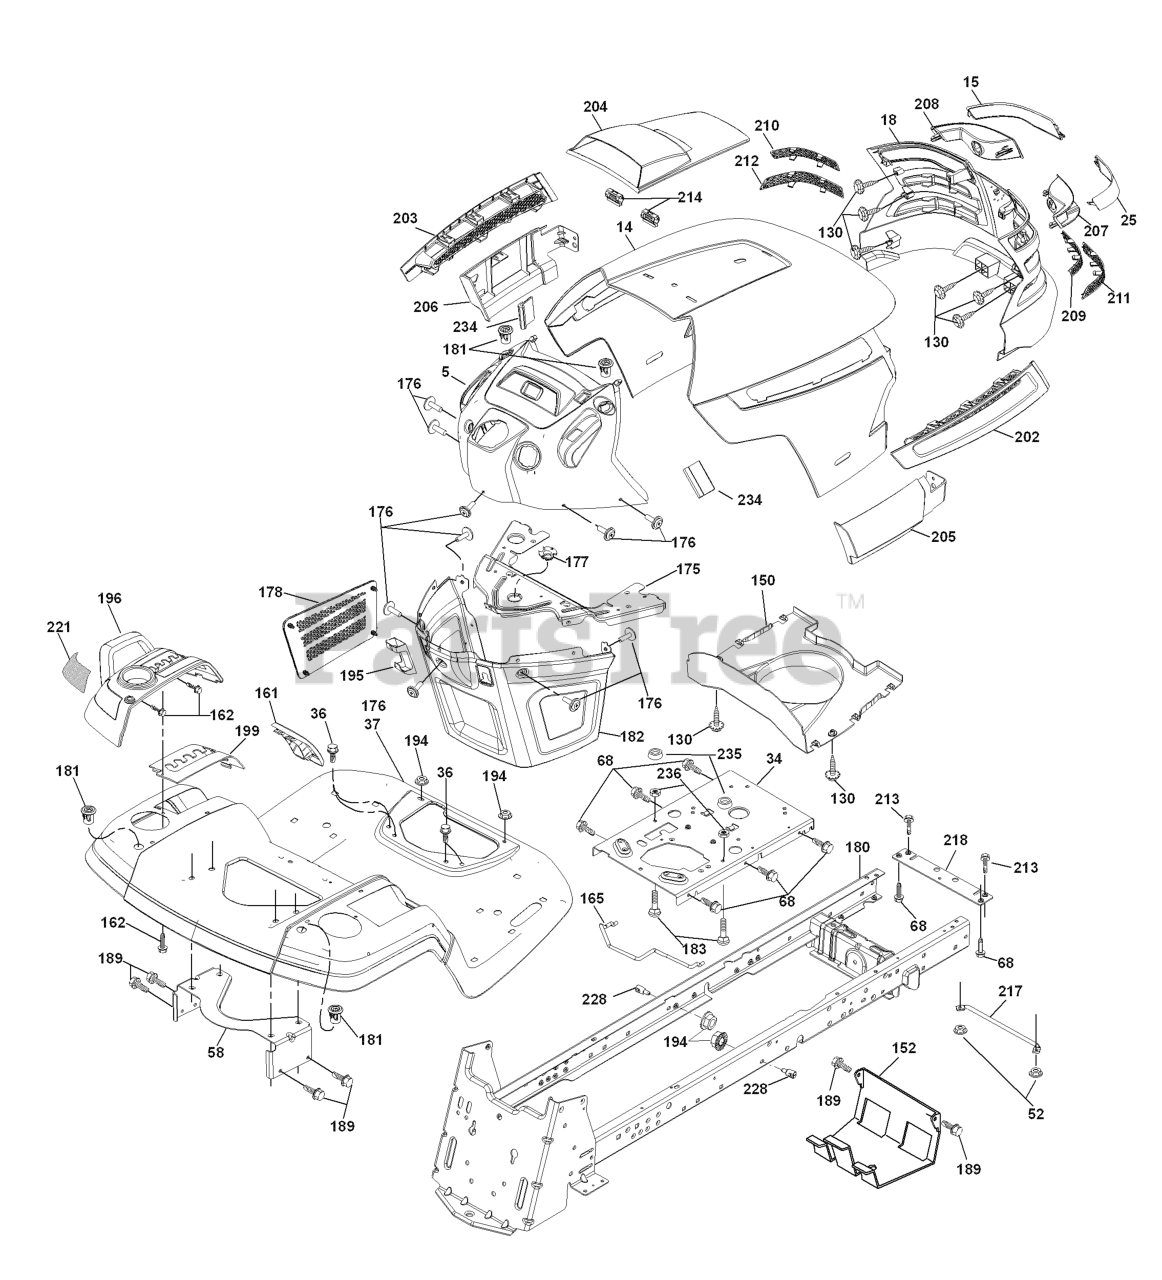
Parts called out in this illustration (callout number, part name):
5	DASH.ASM.HUSQ.GT.E.RECT.W/CK
14	HOOD
15	LENS.LH.TEX.GT.HUSQ.CL
18	GRILL.ASM.HUSQ.TG/CRD.W/TRIM
25	LENS.RH.TEX.GT.HUSQ.CL
34	PLATE.ENGINE.WELDED.CHASSIS
36	SCREW 5/16"
37	FENDER.PNT.TX.GT.CH/FW.ORANGE
52	LOCKNUT
58	BRKT.SUPPORT.FNDR/TANK
68	Screw 5/16-18 x 1/2
130	SCREW.#10 X 0.750.BOS
150	AIR.DUCT.HOOD.TEX.GT.HUSQ
152	SHIELD.BROWNING.W/TEX
161	CONSOLE.FUEL.WINDOW.HU
162	SCREW.HI-LO.CONSOLE
165	SUPPORT.TANK.REAR.W/TEX
175	PLATE.CROSSMEMBER.HUSQ
176	SCREW.#10-24X5/8.RN.QU
177	BUSHING, STEERING
178	CARGO.ASM.NET.TXGT.W/C
180	CHASSIS.GT.SLOPED.DRAWBAR.
181	BUSHING.MNT.FEND.CRGO.
182	DASH.LOWER.COMMON.12V.ADAPTOR
183	BOLT.5/16-18X1-1/4 FULL.THREAD
189	SCREW
194	NUT LOCK HEX FLANGE 5/16-18
195	PLUG.N/CRUISE.COMMON.YT/GT.BLK
196	CONSOLE.ASM.DCKLFT.W/RF.HQ.DLR
199	PLATE.DECK.LIFT.HUSQVARNA.GT
202	VENT.SIDE.HOOD.HUSQ.RH.GREY
203	VENT.SIDE.HOOD.HUSQ.LH.GRAY
204	VENT.ASM.TORPHD.HUSQGT.LOGO.CL
205	SKIRT.HOOD.SIDE.HUSQ.RH.GREY
206	SKIRT.HOOD.SIDE.HUSQ.LH.GREY
207	BEZEL.RH.TEX.GT.HUSQ
208	BEZEL.LH.TEX.GT.HUSQ
209	INSERT.HEX.GRILL.HUSQ.GREY
210	INSERT.HEX.GRILL.HUSQ.
211	INSERT.HEX.GRILL.HUSQ.
212	INSERT.HEX.GRILL.HUSQ.
213	BOLT
214	CLIP.RETAINER.TINNER.
217	ROD.PIVOT.HOOD
218	X-PIECE.HOOD.STOP.NON/
221	REFLECTOR.LH.TEX GT HU
228	STUD.FASTNER.W/ANTI-ROTATE
234	BUMPER.HOOD.TEX.HUSQVARNA
235	SPACER FENDER
236	NUT.CENTERLOCK.5/16-
